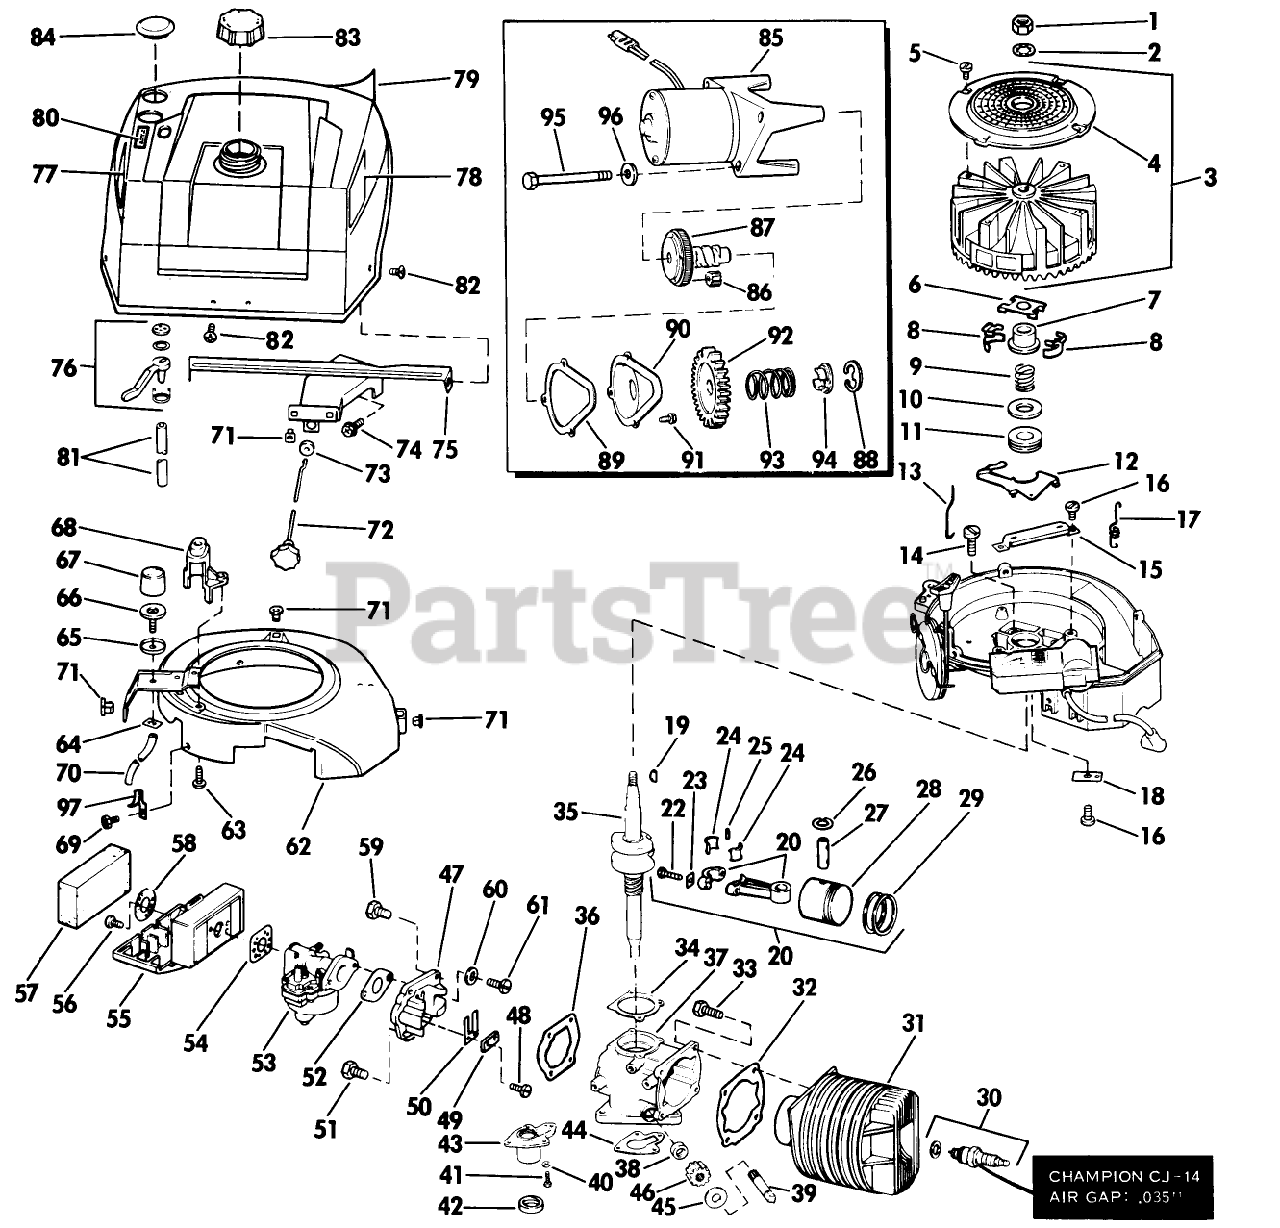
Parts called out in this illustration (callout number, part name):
4	SCREW F
7	COLLAR S
9	SPRING S
12	LEVER-GOVERNOR S
15	BRACKET
16	SCREW S
24	LINER ASM
26	RING-RETAINING
30	Spark Plug
32	GASKET S
34	GASKET S
36	GASKET S
43	GEAR COVER S
44	GASKET-CVR S
45	THRUST WASHER
46	GEAR, DR SHAFT S
47	REED PLATE AY. S
49	PLATE-BACKUP, REED
51	SCREW S
52	GASKET S
54	GASKET S
56	SCREW S
57	AIR FILTER S
58	WASHER S
59	SCREW S
64	LOCKNUT S
65	CUP-BULB
71	NUT-CLIP
74	SCREW S
75	BRACKET
82	SCREW S
88	RET.RING EF
